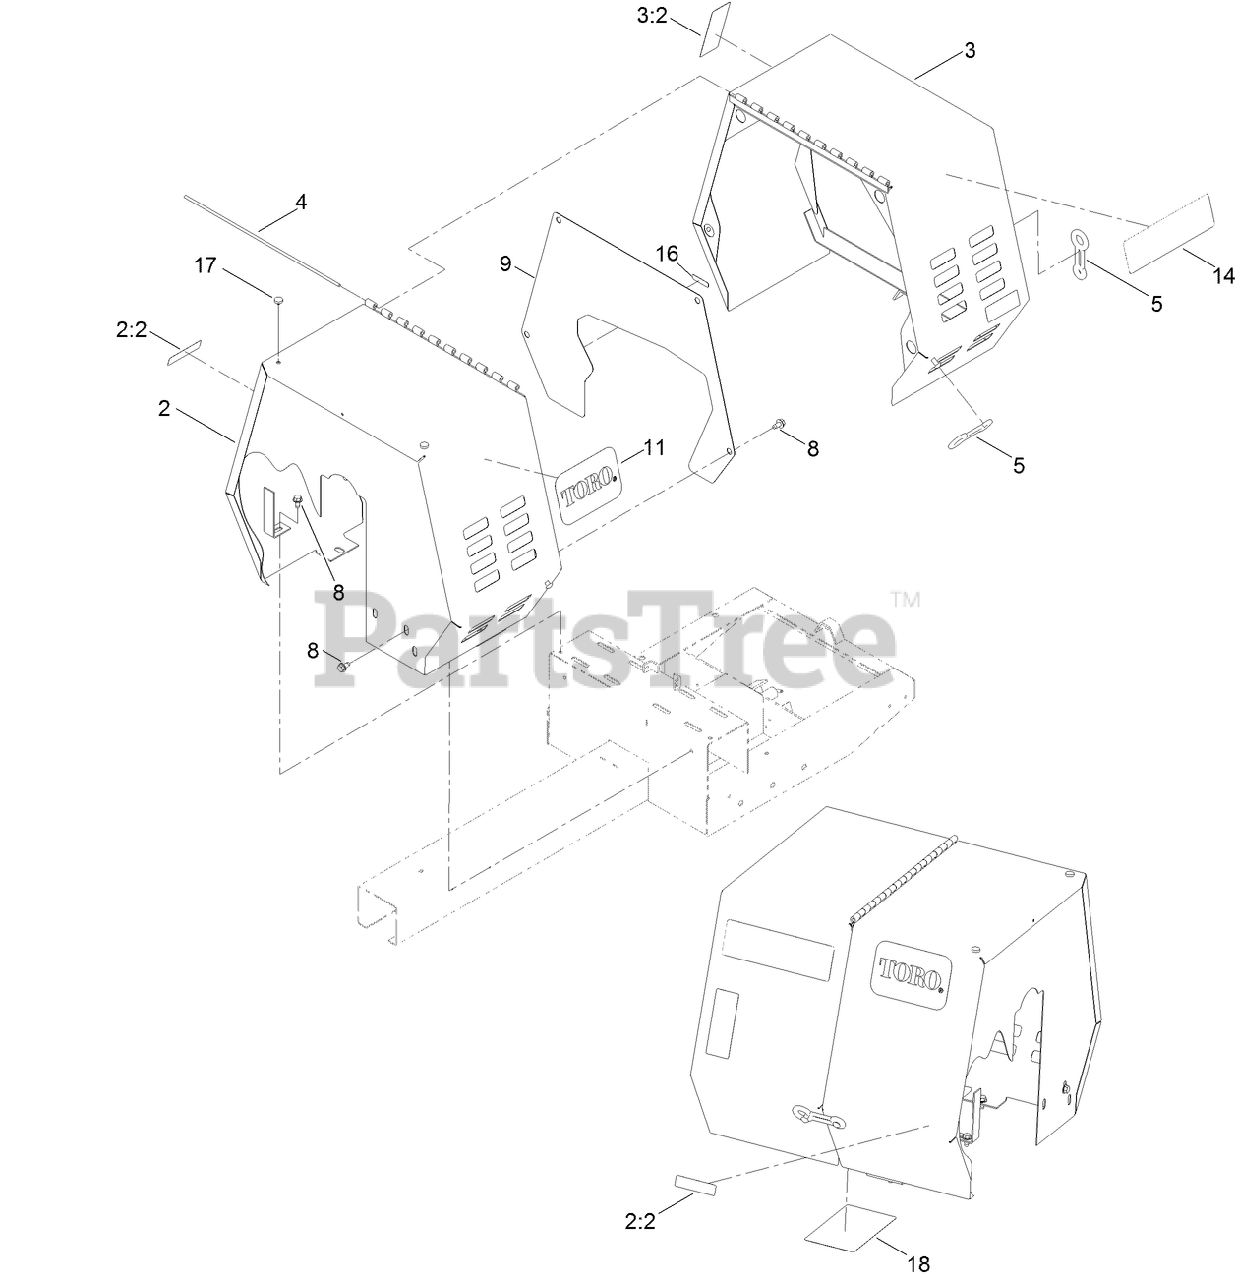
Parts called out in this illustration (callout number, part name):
2	STATIONARY COWL ASM
2:2	DECAL-ARRESTOR, SPARK
3	MOVABLE COWL ASM
3:2	DECAL-WARNING
5	LATCH-RUBBER
8	SCREW-HWH
9	PLATE-ACCESS, BELT
11	DECAL
16	DECAL-GREASE
17	BUMPER
18	DECAL-SERVICE
